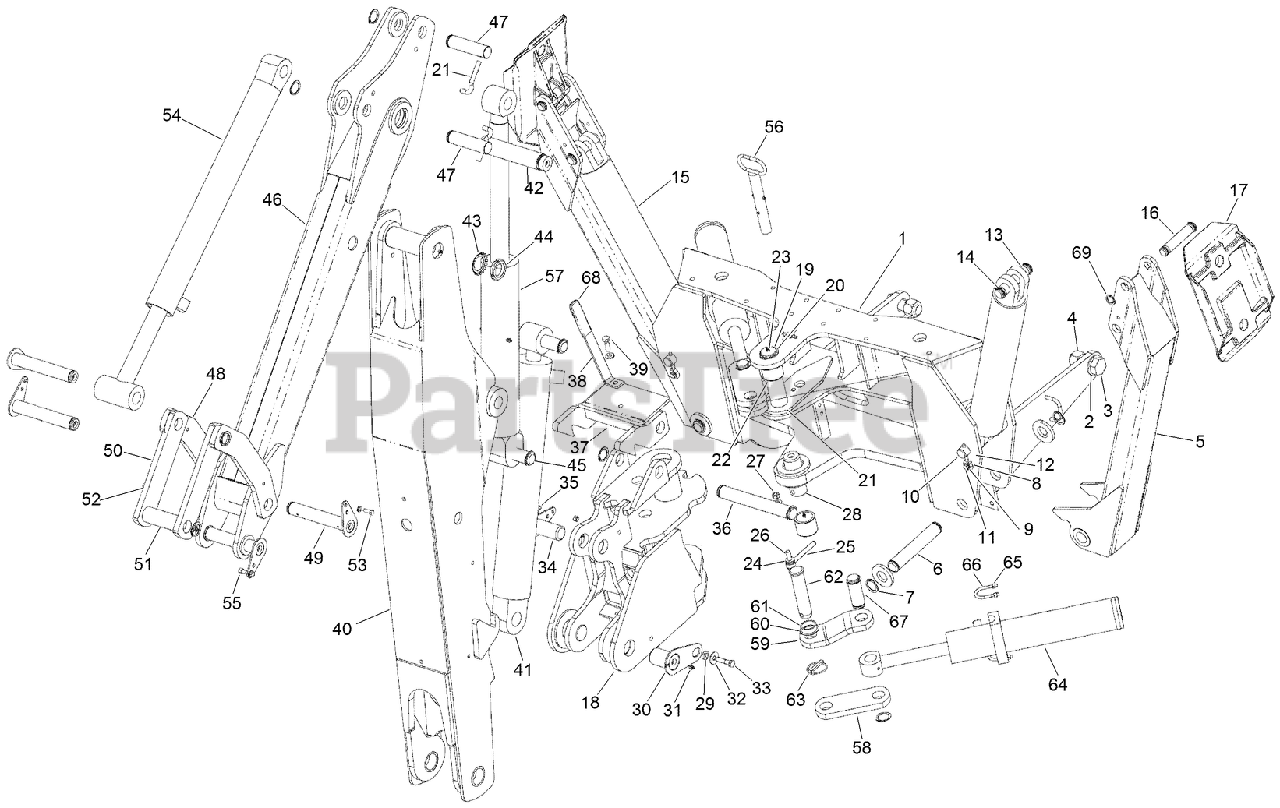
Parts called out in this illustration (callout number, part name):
1	WELDMENT - Frame, Backhoe
5	WELDMENT - Stabilizer Arm
6	PIN (STABILIZER TO FRAME)
8	PIN-RETAINER
9	WASHER-FLAT
10	PIN (CYLINDER TO FRAME)
11	BOLT-hex, 3/8 NC x 1-1/2 inch
12	NUT-HEX
13	PIN-STABILIZER (CYLINDER ROD END)
14	RING-RETAINING
15	CYLINDER - Hydraulic
16	PIN (STABILIZER PAD END)
17	PAD-Stabilizer Cast
18	WELDMENT - Swing Tower, Backhoe
19	PIN (TOP SWING PIVOT)
20	RING-RETAINING, EXTERNAL
21	PIN-RETAINER
22	BUSHING
23	FITTING-Lube 1/4-28 Tpr SAE-LT .54 Long
24	WASHER-FLAT
25	PIN-RETAINER
26	BOLT-Hex Hd 0.500 x 2.25 GR8 ZND
27	NUT-LOCK, HEX
28	PIN (LOWER SWING PIVOT)
29	SPACER-PIN
30	PIN (BOOM PIVOT)
31	FITTING-Lube 1/8-27 Dryseal PTF
32	WASHER-FLAT
34	PIN-BOOM (CYLINDER)
35	BOLT - Round Hd .375 x 1.50 GR5 ZND
36	PIN (LATCH TO SWING TOWER)
37	WELDMENT - Latch, Boom Lock
38	HANDLE-Control
39	SCREW-HH
40	WELDMENT - Backhoe Boom
41	CYLINDER - Boom
42	PIN (DIPPER PIVOT)
43	WASHER-BEARING, LOCK
44	NUT - Bearing Lock, CAD Pltd
45	PIN-DIPPER (CYLINDER TO BOOM PIN)
46	DIPPER Assembly
47	PIN (DIPPER CYLINDER)
48	LINK - Curved, Bucket
49	PIN-BUCKET
50	LINK - Straight, Bucket
51	SPACER - Bucket Links
52	WASHER-Spring Lock, Reg 3/8 ZND
53	SCREW-HH
54	CYLINDER - Bucket
55	BOLT-Hex Hd .375 x 1.75 GR5 ZND
56	LOCKING SWING PIN ASM
57	CYLINDER - Dipper
58	SWING LINK - Straight
59	LINK - Swing Offset
60	WASHER
61	SPACER-LINK, SWING
63	PIN-KLIK
64	CYLINDER - Swing
65	NUT-HEX
68	GRIP-HANDLE
69	RING-RETAINING
